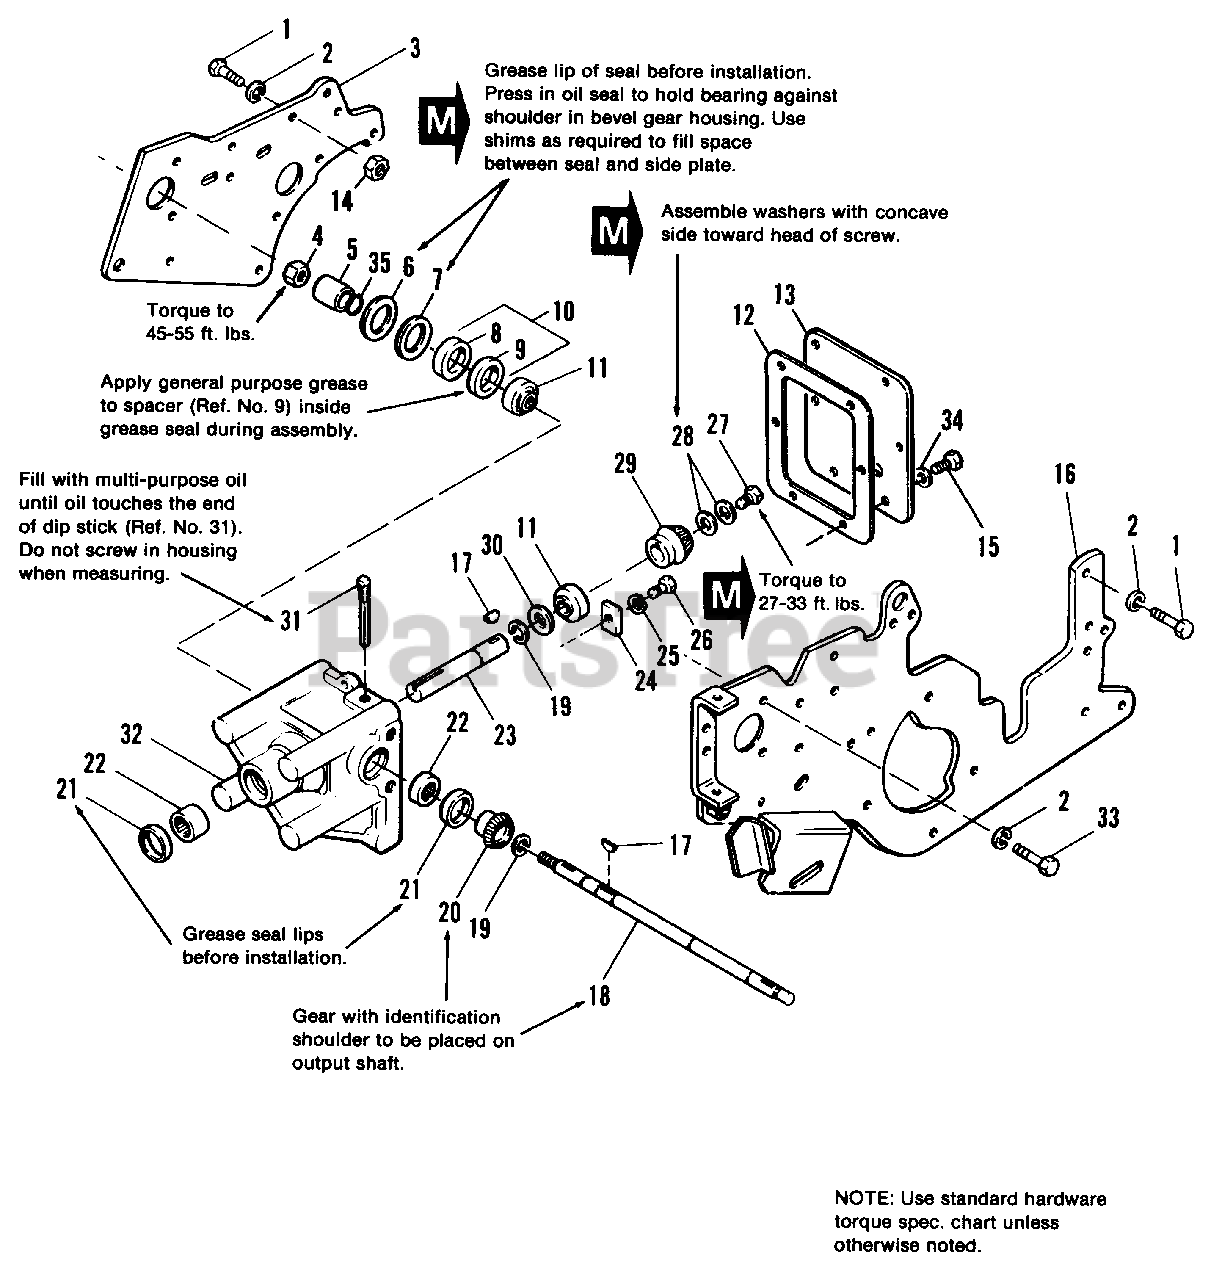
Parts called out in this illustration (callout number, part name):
1	CAPSCREW, Hex Hd., 7/16-14 x 1-1/4
2	LOCKWASHER, 7/16
3	PLATE, Side, R.H.
4	LOCKNUT, Hex, Jam, 3/4-16
9	SPACER, Seal, Oil
10	REPAIR KIT, Seal (Incl. Ref. Nos. 8 & 9)
11	BEARING, Ball
14	NUT, Hex, 7/16-14 x 1
15	CAPSCREW, Hex Hd., 1/4-20 x 5/8
16	PLATE ASSY., Side, L.H.
17	KEY, Woodruff, #9
18	SHAFT, Driven (Incl. Ref. Nos. 4 & 17)
19	RING, Retaining
20	GEAR, Bevel, Driven
22	BEARING, Needle
23	SHAFT, Driver
24	PLATE, Bearing, Clamp
25	LOCKWASHER, 5/16
26	CAPSCREW, Hex Hd., 5/16-18 x 5/8
27	CAPSCREW, Hex Hd., 5/16-18 x 3/4
29	GEAR, Bevel, Driver
32	HOUSING, Bevel Gear
33	CAPSCREW, Hex Hd., 7116-14 x 1
34	LOCKWASHER, 1/4, I.D.
